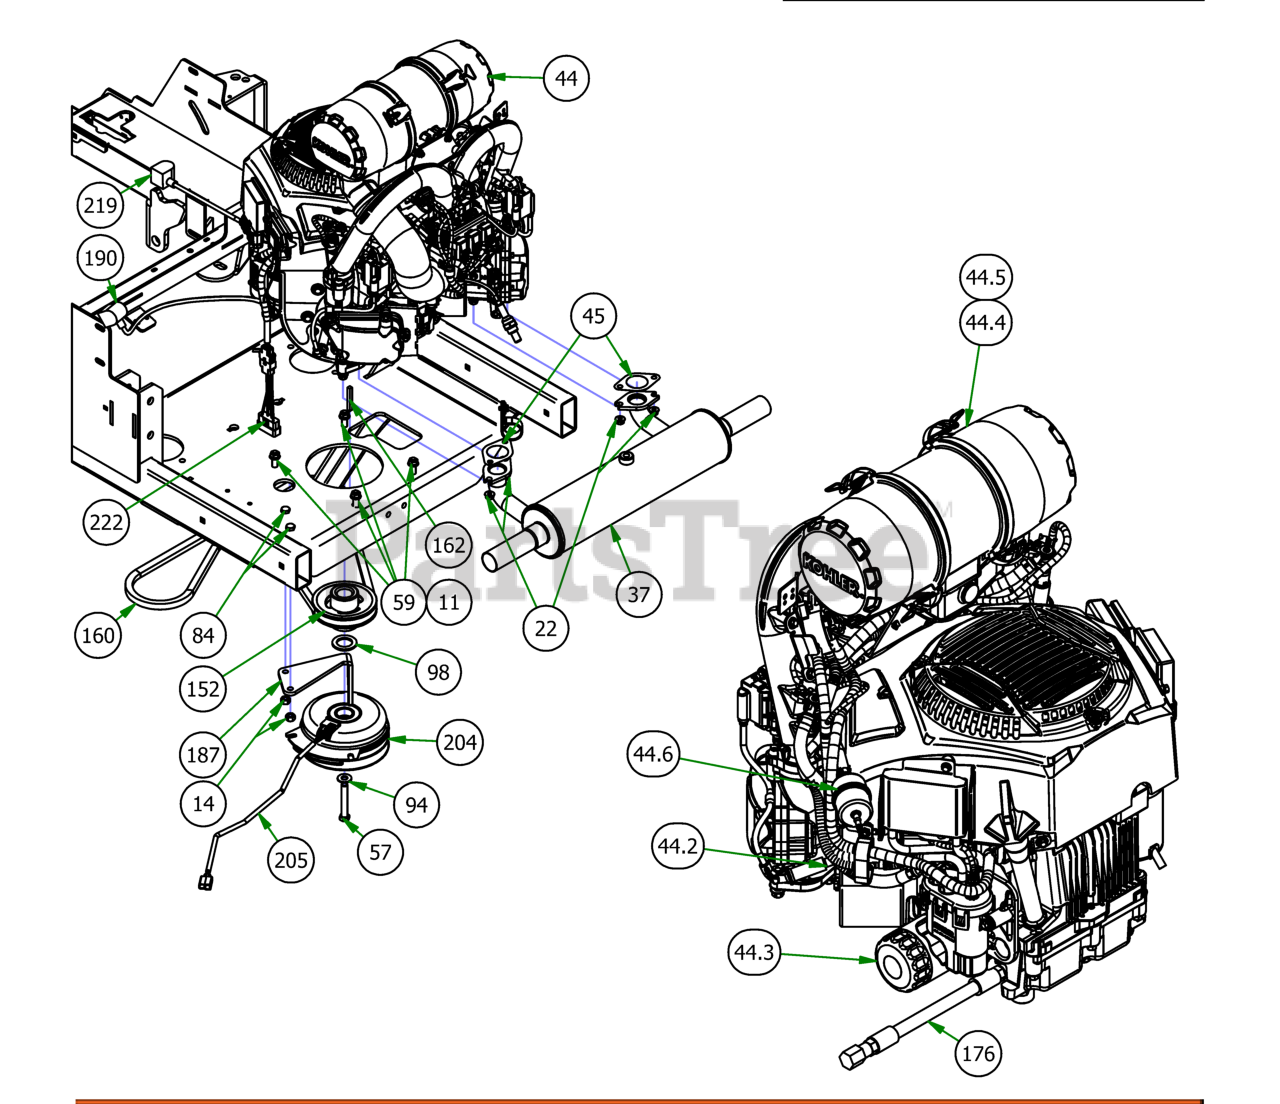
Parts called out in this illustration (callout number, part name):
11	3/8-16 HEX SERRATED FLANGE NUT HARD/ZINC
14	3/8" Hex Nut
22	M8 Flange Nut for Kohler Exhaust
37	Muffler for 33Hp 824cc Kohler Engine
44	824cc EFI Kohler
44.2	Spark Plug
44.3	Oil Filter
44.4	Canister Air Filter- Inner
44.5	Canister Air Filter- Outer
44.6	25/26 HP Kohler Fuel Filter
45	Exhaust Gasket for 824EFI Kohler
49	M6-1.0 X 12MM DIN 933 HEX TAP BOLT (CL 8.8) ZINC
57	7/16-20 x 2 3/4 Hex C/S GR 8 Yellow Zinc
59	3/8 x 1 1/8 bolt
82	3/8 x 1 1/2 Bolt
84	3/8" x 1" Hex Bolt
94	3/8 FLAT WASHER USS (1" OD) ZINC
98	1 1/8" Flat Spacer
100	1/4 USS Flat Washer Zinc
152	4 3/4 Motor Pulley
160	2019 Rogue Pump Belt 68"
162	1/4 x 2 Square key Stock
176	Oil drain Hose
187	PTO Engager Holder
190	24" Red Battery Cable
204	Clutch Assembly
205	Clutch Pigtail
206	2019 Veritical Suspension Frame
208	Diesel Hydraulic Hose Clamp
219	Starter Cable
222	2019 Harness Adaptor - Vanguard 37 EFI Vert/Horiz
